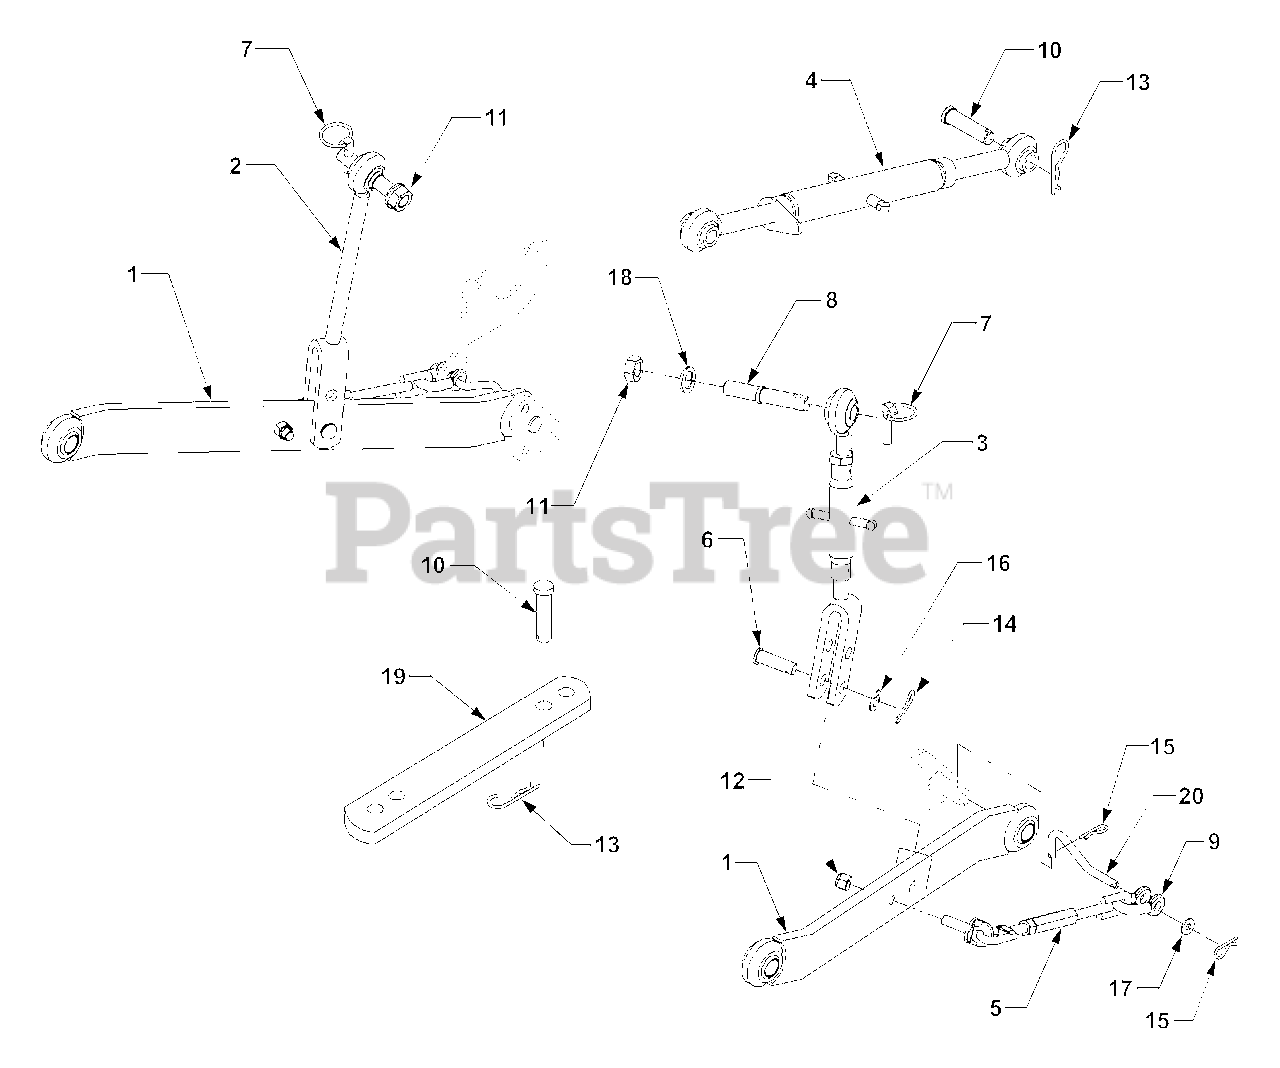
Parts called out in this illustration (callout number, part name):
3	Link, Lift - Adjustable
4	Link, Upper Center
5	Chain Assembly, Check
6	Pin, Clevis, .624 Dia.
7	Pin, Klik, 1.75 Lg.
8	Pin, Upper Lift Arm
9	'U' Clevis, Check Chain
10	Pin, Clevis, .75 x 2.75
11	Nut, Hex, 3/4-10 GR5
12	Nut, Hex Insert Lock, 1/2-20
13	Pin, Internal Cotter, .148 x 3.0
14	Pin, Internal Cotter, .125 x 1.75
15	Pin, Internal Cotter
16	Washer, Flat, .635 x 1.12 x .09
17	Washer, Flat, .385 x .87 x .09
18	Washer, Lock, 3/4
